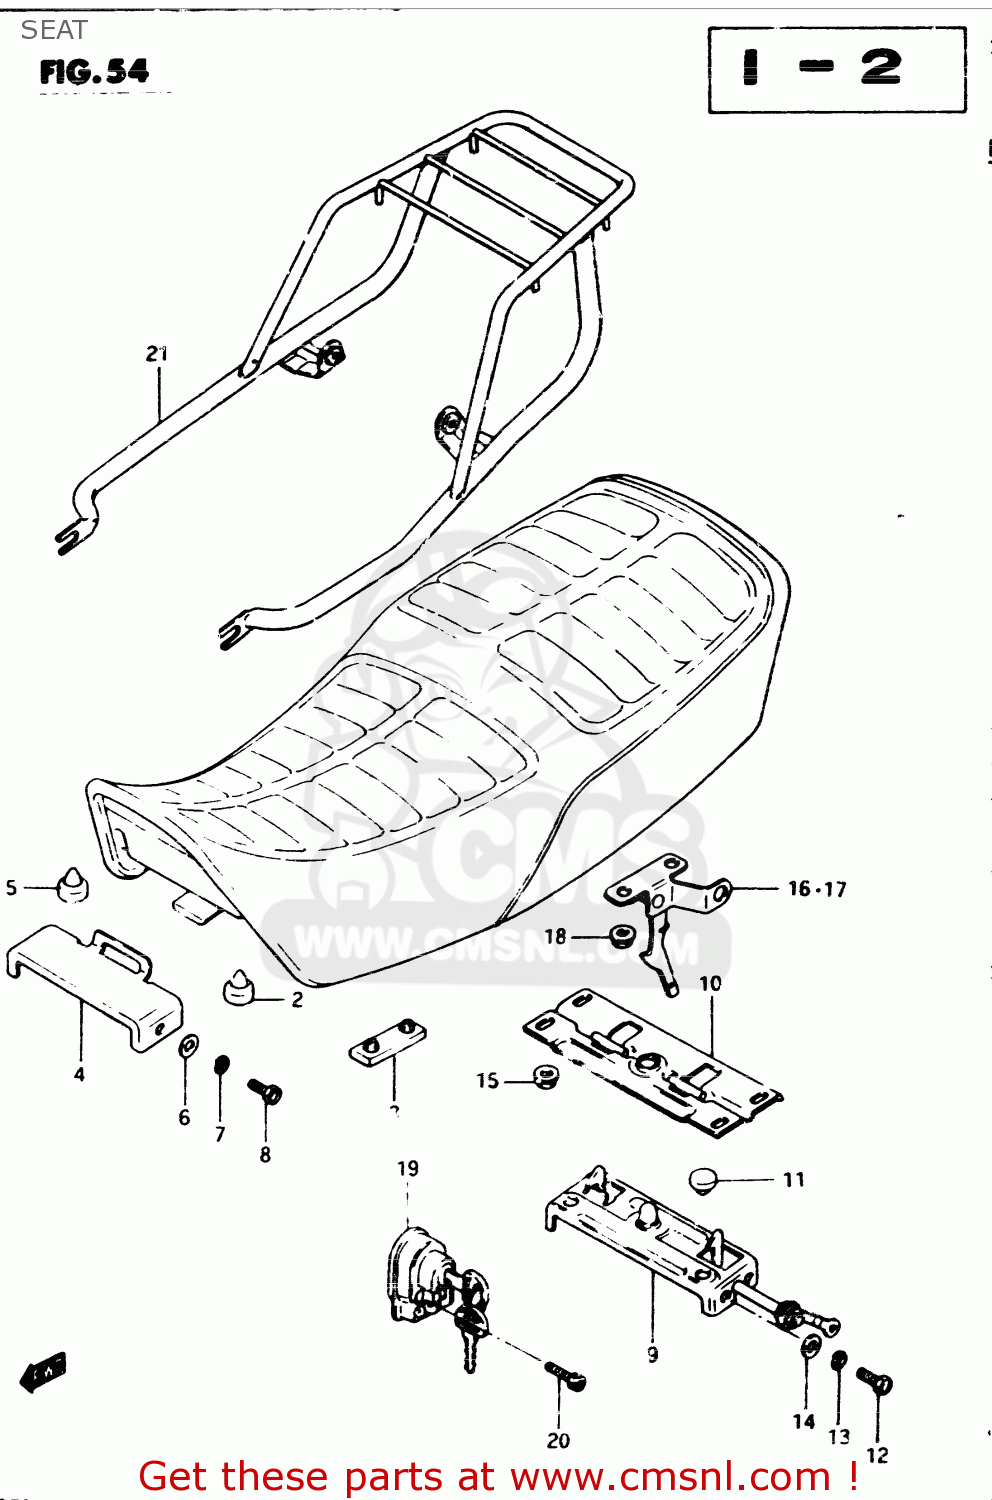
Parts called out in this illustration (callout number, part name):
1	SEAT ASSY (BLACK)
2	CUSHION
3	CUSHION
4	PLATE,SEAT LOCK,FRONT
5	CUSHION(11.5X22X20)
6	WASHER
7	LOCK WASHER
8	BOLT
9	PLATE,CLAMP GUIDE
10	PLATE,SEAT CLAMP GUIDE
11	CUSHION
12	SCREW
13	LOCK WASHER
14	WASHER
15	NUT
16	LEVER,SEAT HOOK,RIGHT
17	LEVER,SEAT HOOK,LEFT
18	NUT
19	LOCK ASSY,HELMET
20	BOLT 5X25
21	CARRIER
